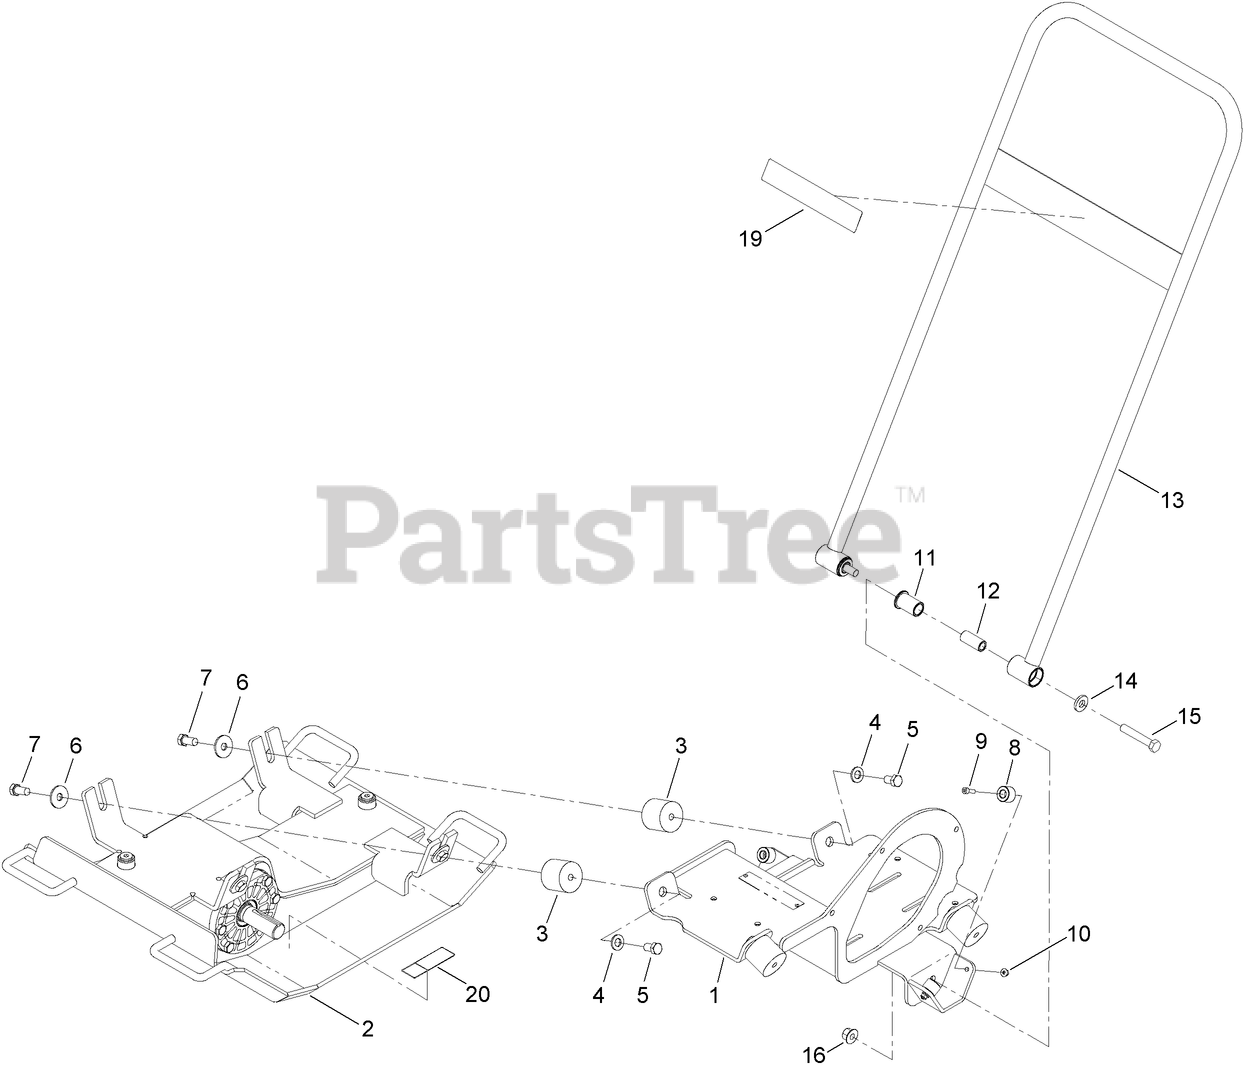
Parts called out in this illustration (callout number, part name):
1	DECK-ENGINE
2	BASE ASM
3	MOUNT-SHOCK
4	WASHER-FLAT
5	SCREW-HH
6	WASHER-FLAT
7	SCREW-HH
8	SPACER-STOP, HANDLE
9	SCREW-HSH
10	NUT-HF
11	BUSHING-HANDLE, MAIN PLATE
12	SPACER-HANDLE, PIVOT
13	HANDLE-MAIN
14	WASHER-FLAT
15	SCREW-HH
16	NUT-LOCK, HHF
20	DECAL-WARNING, SHIELDS
